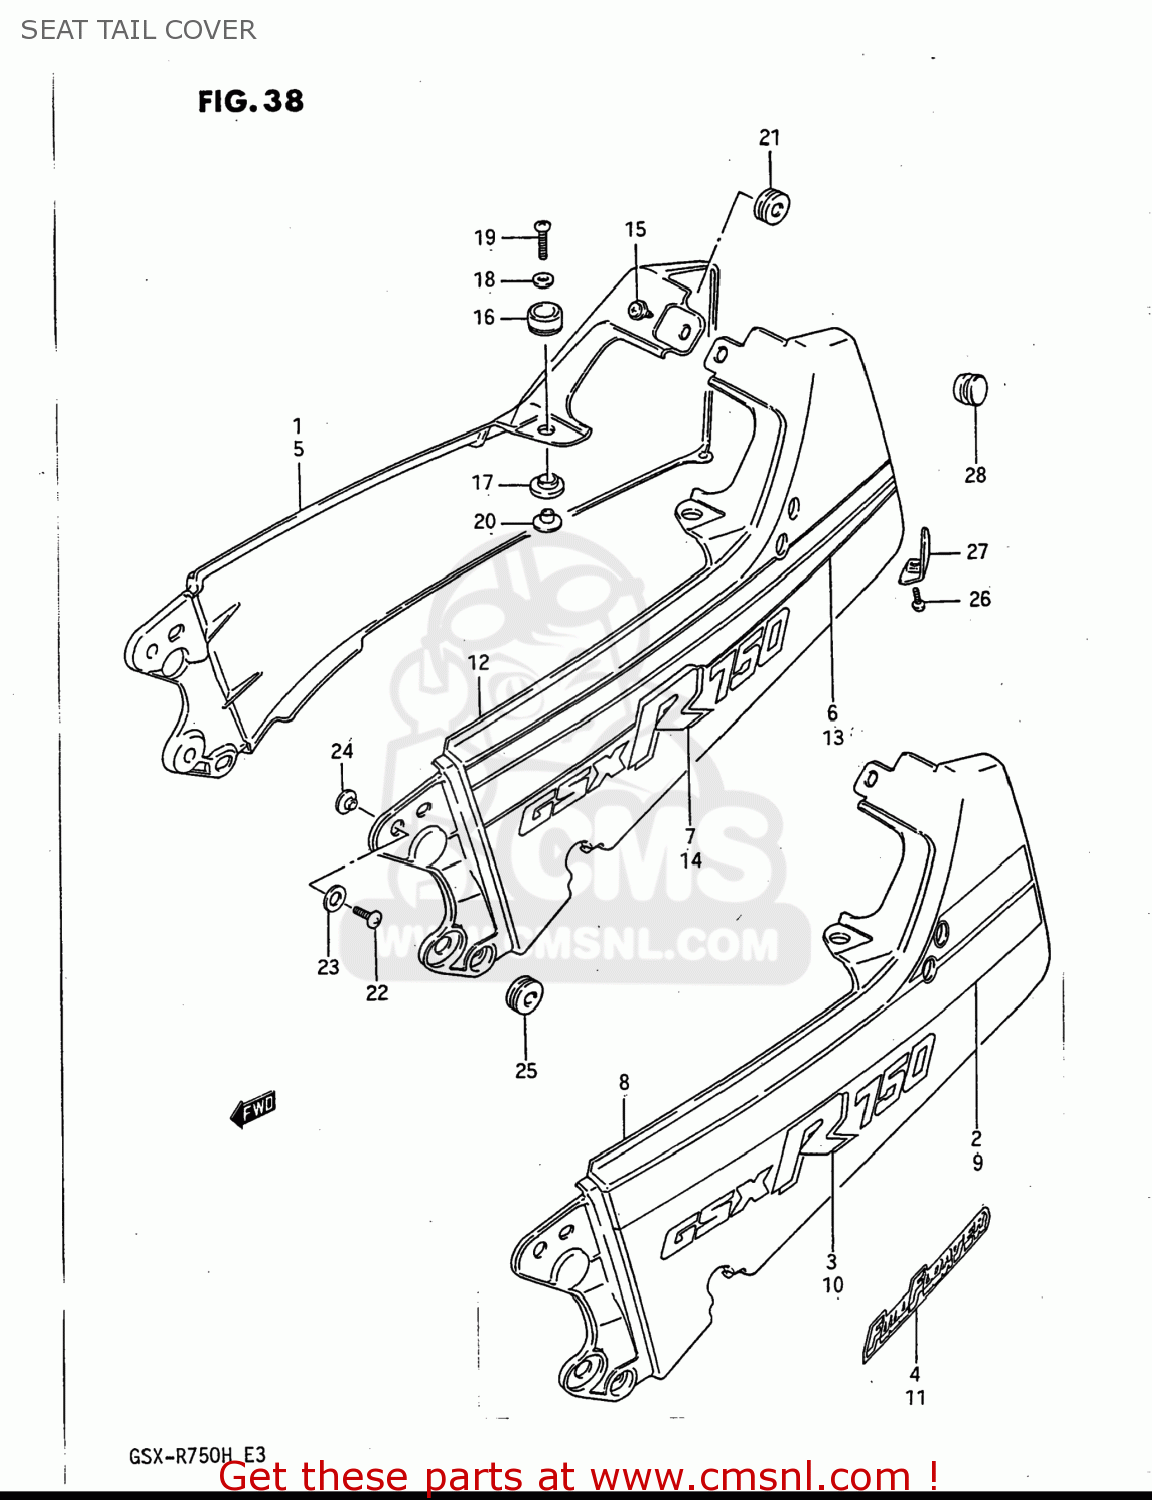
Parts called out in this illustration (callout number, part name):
1	COVER,SEAT TAIL
2	TAPE SET,SEAT TAIL COVER
3	EMBLEM
4	EMBLEM
5	COVER COMP,SEAT TAIL
6	TAPE SET,SEAT TAIL COVER
7	EMBLEM
8	COVER,SEAT TAIL
9	TAPE SET,SEAT TAIL COVER
10	EMBLEM
11	EMBLEM
12	COVER,SEAT TAIL
13	TAPE SET,SEAT TAIL COVER
14	EMBLEM
15	CLIP
16	CUSHION,TAIL COVER UPR
17	CUSHION,TAIL COVER LWR
18	WASHER
19	SCREW
20	SPACER,SEAT TAIL COVER
21	CUSHION
22	SCREW
23	WASHER
24	WASHER
25	CUSHION
26	SCREW
27	PLATE,SEAT TAIL COVER,L
28	CAP,SEAT TAIL COVER
